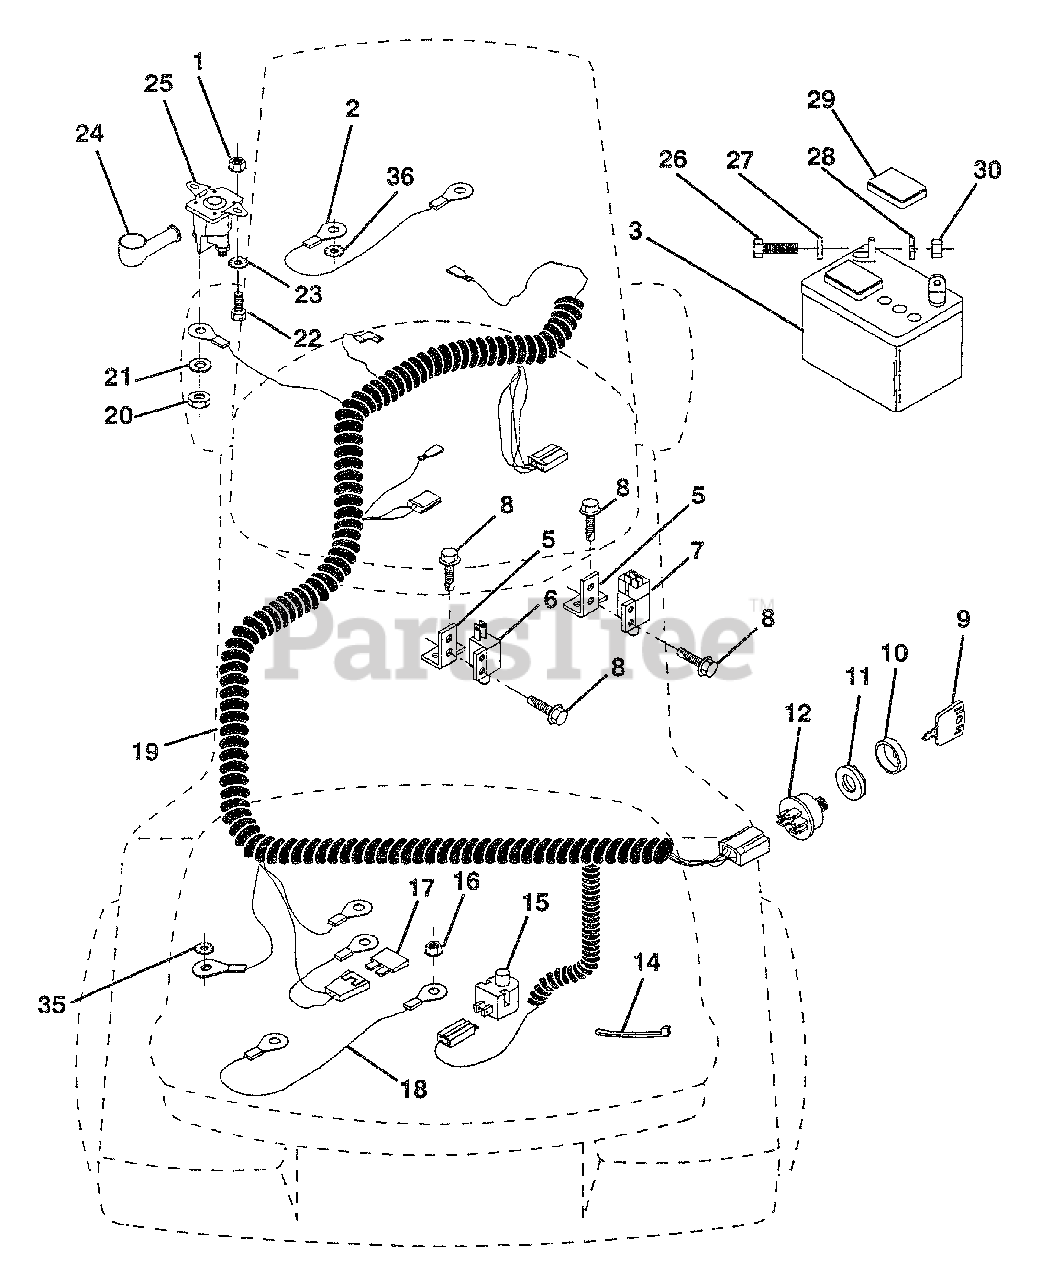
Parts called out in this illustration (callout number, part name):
1	Nut, Hex Keps 1/4-20
2	Assembly, Cable
3	Battery
5	Bracket, Switch
6	Switch, Interlock (2-terminal)
7	Switch, Interlock (4-terminal)
8	Screw, Hex Hd. Tap #10-24 x 1/2
9	Key, Molded
10	Cover, Key Ignition
11	Nut, Ignition
12	Switch, Ignition
14	Tie, Cable
15	Switch, Plunger
16	Nut, Hex, Keps 5/16-18
18	Assembly, Cable
19	Harness, Ignition
20	Nut, Hex Jam 1/4-20
21	Washer, Lock 1/4
22	Bolt, Fin. Hex 1/4-20 UNC x 1/2 Gr. 5
23	Washer, Lock Ext. Tooth 1/4
24	Cover, Terminal
25	Solenoid
26	Bolt, Hex Hd. 1/4-20 UNC x 3/4.
27	Washer 9/32 x 5/8 x 16
28	Washer, Lock 1/4
29	Cap, Battery
30	Nit, Fin. Hex 1/4-20 UNC
35	Washer Lock Ext. Tooth 3/8
36	Washer Lock Inter. Tooth 1/4
